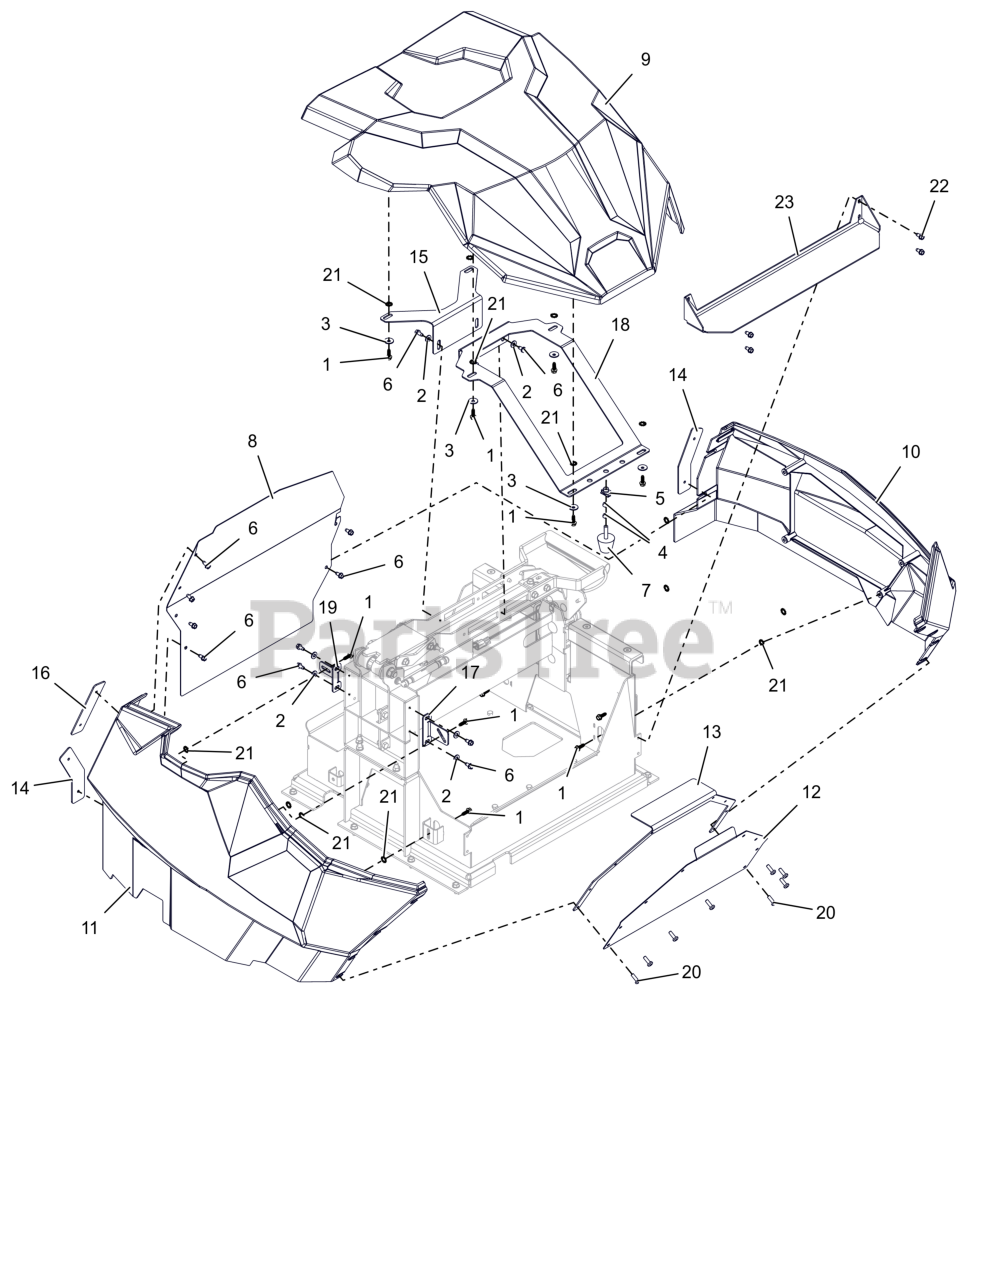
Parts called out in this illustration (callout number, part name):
1	SCR, PLASTITE .25-10X.75 ZCC
2	WSHR,FLT .281X.625X.065 ZCC
3	WSHR,BLVL-.250X.815X.061 ZFS
4	NUT-JAM .312-18 G2 ZCC
5	NUT-CLIP RETAINER 5/16-18X.56
6	SCR-TAP .25-20X.50 HWH ZCC
7	BUMPER, STUD MOUNTED CONE SHAPED
8	BRKT, FENDER - REAR (BLACK)
9	HOOD, BATTERY CAPTURE
10	FENDER, BATTERY CAPTURE - LH
11	FENDER, BATTERY CAPTURE - RH
12	BRKT, FENDER - FRONT (ORANGE)
13	PLATE, BACK - FRONT (BLACK)
14	PLATE, BACK REAR LH (BLACK)
15	SUPPORT, HOOD (BLACK)
16	PLATE, BACK - REAR UPPER (BLACK)
17	SUPPORT, FENDER (BLACK)
18	SUPPORT, HOOD (BLACK)
19	SUPPORT, FENDER (BLACK)
20	SCR-TAP 1/4-20X3/4 LPAN TL BZ
21	WSHR,LK-EXT .326X.599X.031 ZCC
22	SCR-TAP .25X.50 HWH ZB500
23	BRKT, STORAGE (ORANGE)
